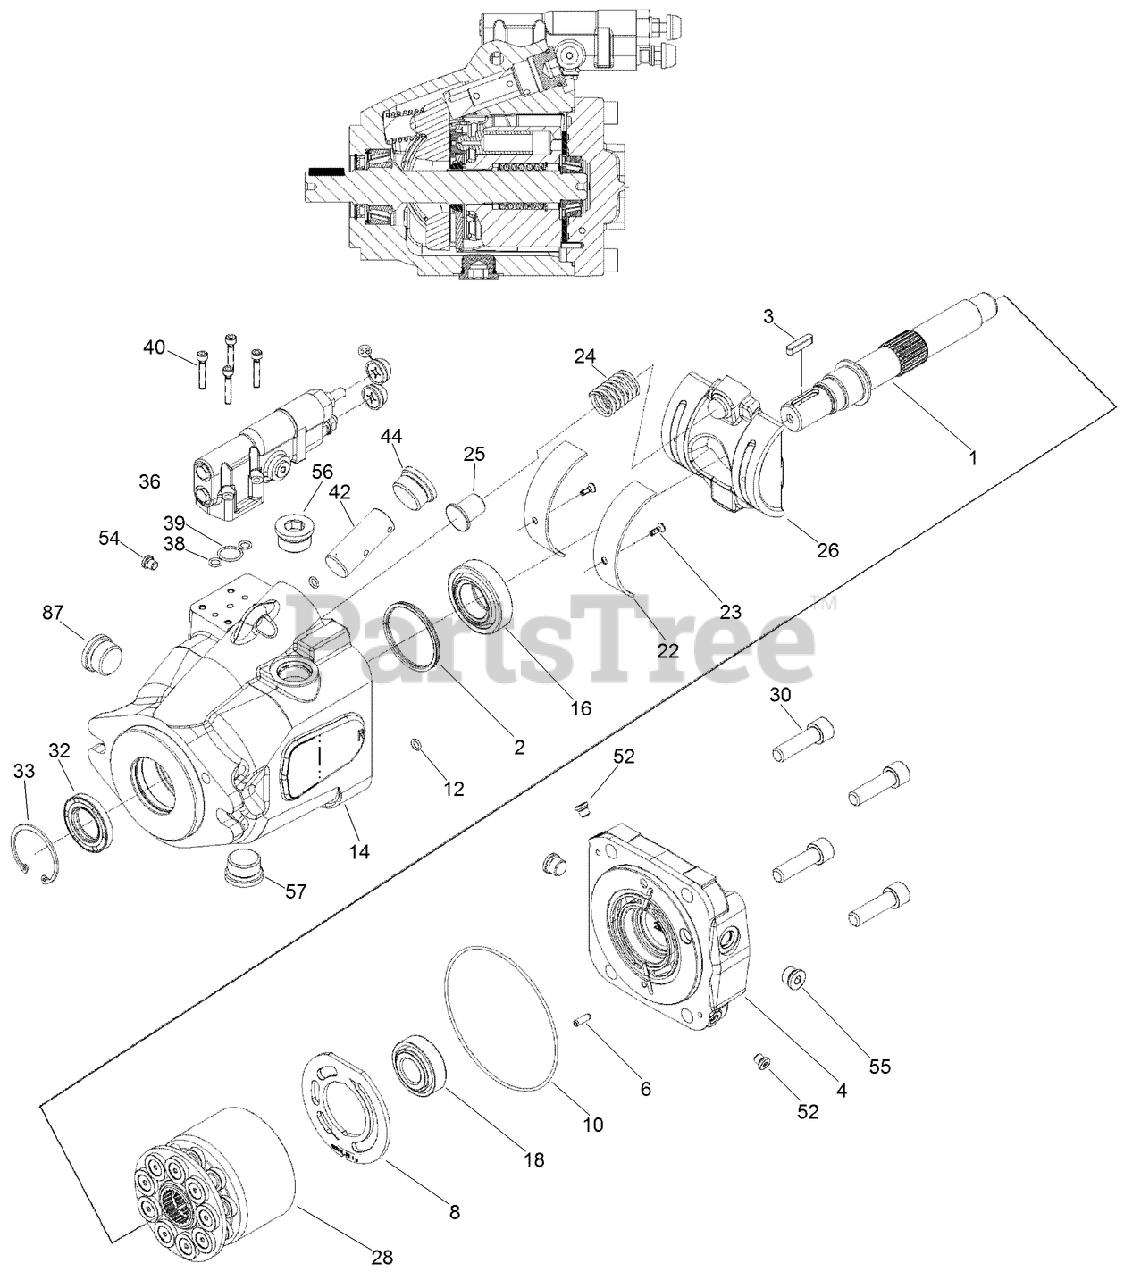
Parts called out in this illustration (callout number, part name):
1	SHAFT - Drive, Input, 15 Tooth, 16/32, 1.81 Ext
2	RING, Crush
3	Key
6	PIN - Roll (Valve Plate)
8	PLATE - Valve (RH)
10	O-RING - End Cover Pilot
12	O-RING - End Cover / Housing
14	HOUSING
16	BEARING ASSEMBLY - Shaft (Front)
18	BEARING ASSEMBLY - Shaft (Rear)
22	BEARING - Swash Plate
23	SCREW - Cap, Socket, Flat, CSK (Swash Bearing)
24	SPRING - Bias
25	BUSHING - Spring
26	PLATE - Swash
30	SCREW - Cap, Housing / End Cover
32	SEAL - Shaft, Standard Polyacrylate
33	RING - Retaining, Internal, Shaft Seal
36	COMPENSATOR
38	O-RING - Compensator
39	O-RING - Compensator
40	SCREW - Cap, Compensator Mounting
42	PISTON - Control
44	PLUG - External Manual Stroke Adjuster
52	PLUG - End Cover
54	PLUG - Housing
55	Plug
56	Plug
57	PLUG - Bottom Case Drain Port
87	Plug
